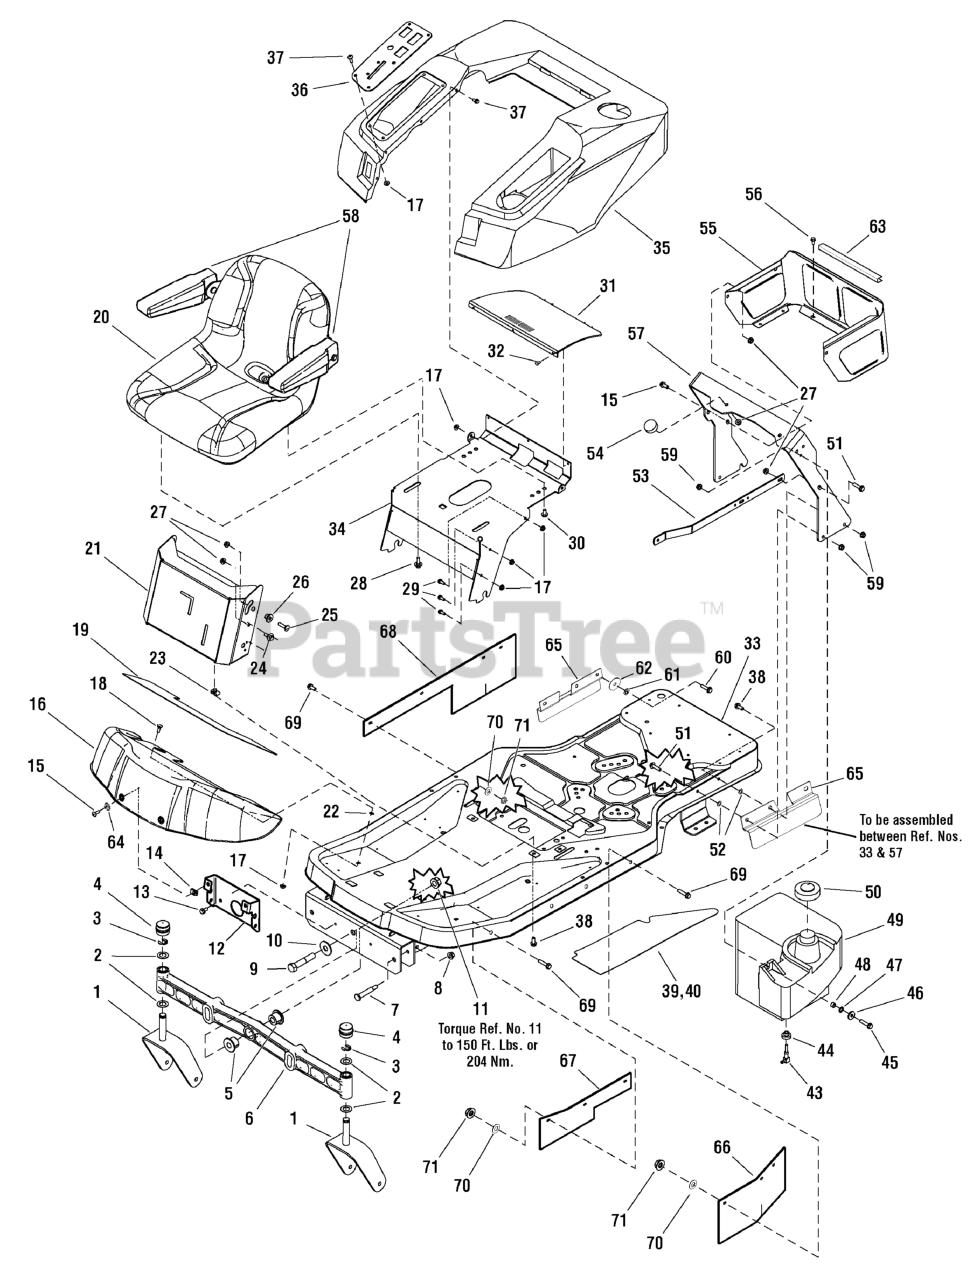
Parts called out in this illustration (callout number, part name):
1	CASTER ASSEMBLY
2	WASHER, 3/4 ID x 1.6 OD x .05 THK
3	RING, Klipring, 3/4
4	CAP, Hub
5	BUSHING, Axle Pivot
6	AXLE, Casting
7	BOLT, Shoulder, G5
8	NUT, Hex Flange, 3/8-16 ESNA
9	CAPSCREW, Hex Head, 5/8-11 x 3 1/4
10	WASHER, 5/8, .64 ID x 1-3/4 OD x .11 THK
11	NUT, Hex Flange Two-Way Lock, 5/8-11
12	BRACKET, Front Footrest Support
13	SCREW, Hex Head Taptite, 5/16-18 x 5/8
14	NUT, Speed Lug Type, 1/4-20
15	SCREW, Truss Head Torx, 1/4-20 x 3/4
16	FRONT FOOTREST
17	NUT, Hex Flange, 1/4-20 ESNA
18	CARRIAGE BOLT, 1/4-20 x 3/4, G5
19	PAD, Footrest Panel
20	SEAT ASSEMBLY, with Armrests
21	PANEL, Front with Slot
22	NUT, Push, 1/4
23	NUT, Speed, Lug Type, 5/16-18
24	BOLT, Shoulder
25	BOLT, Carriage, 5/16-18 x 1 1/4
26	PIVOT, Hood, Powdered Metal
27	NUT, Hex Flange Whiz Lock, 5/16-18
28	BOLT, Shoulder, G5
29	SCREW, Hex Whiz Lock Flange, 1/4-20 x 5/8
30	SCREW, Hex Flange Whiz Lock, 5/16-18 x 3/4 Dog PT
31	SCREEN, Seat Deck
32	RIVET, Pop
33	FRAME ASSEMBLY
34	SUPPORT, Seat
35	SEAT DECK, Plastic
36	PLATE, Control
37	SCREW, Truss Head Torx, 1/4-20 x 3/4
38	SCREW, Hex Whiz Lock Flange, 5/16-18 x 3/4
39	PAD, Footrest, R.H.
40	PAD, Footrest L.H.
43	ELBOW, Gas Tank
44	BUSHING, Fuel
45	CAPSCREW, 5/16, 18 x 1-1/2
46	WASHER, 5/16, .34 ID x 1 OD x .13 THK
47	LOCKWASHER, External Tooth, 3/8
48	SPACER, .33 ID x 1/2 OD x 5/16 LG
49	TANK, Fuel
50	CAP, Fuel Tank
51	CAPSCREW, Hex Head, 5/16-18 x 1 1/4
52	NUT, Push Pal, 5/16 DIA Thread, 5/8 OD
53	BRACE, Tank
54	BUMPER, Rubber
55	SHROUD, Rear
56	SCREW, Hex Washer Head Taptite, 1/4-20 x 1/2
57	SUPPORT, Seat Deck
58	ARM REST KIT, L.H & R.H.
59	NUT, Hex Flange Nylock, 5/16-18
60	CAPSCREW, 3/8 - 16 x 1-1/4
61	NUT, Push Pal, 3/8
62	WASHER, 3/8
63	TRIM, 8"
64	WASHER, External Tooth
65	GUARD, Debris
66	GUARD, Rubber, Rear, Left
67	GUARD, Rubber, Front
68	GUARD, Rubber, Rear, Right
69	SCREW, Flange, 1/4-20 x 5/8
70	WASHER, Flat
71	NUT, 1/4-20
